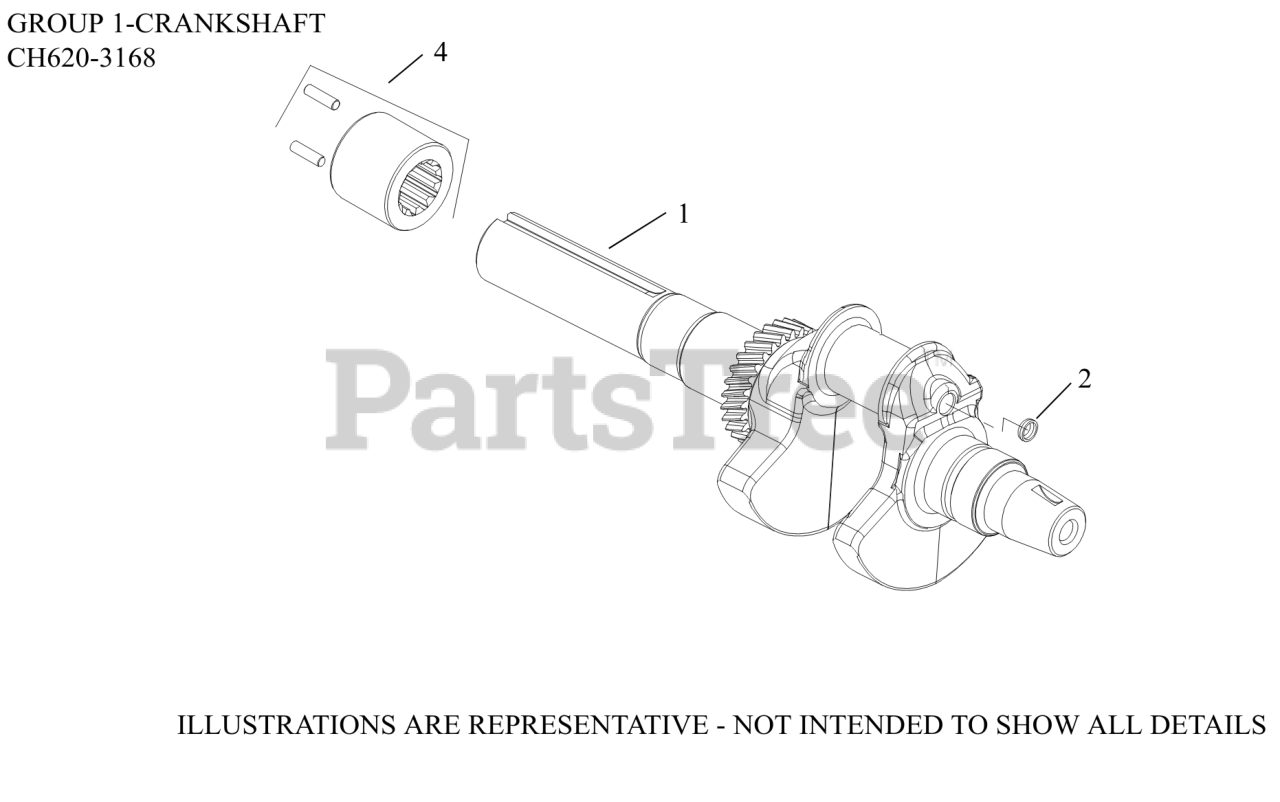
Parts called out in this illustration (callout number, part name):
1	CRANKSHAFT, NON-THRUST STYLE
2	PLUG, CUP
4	KIT, SPLINE
